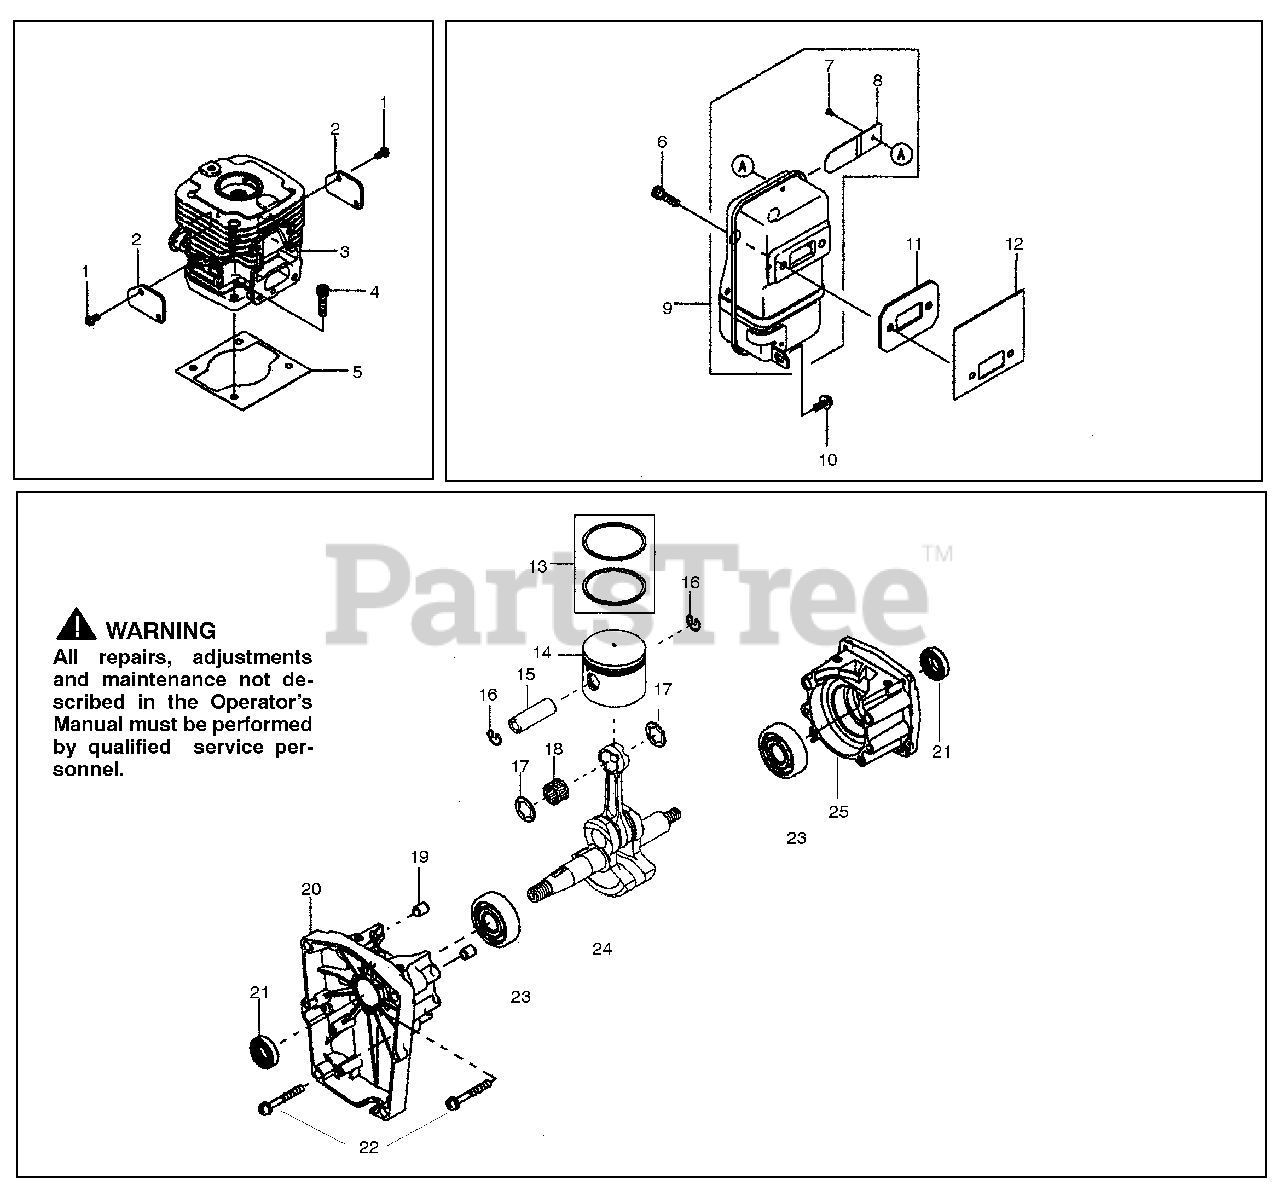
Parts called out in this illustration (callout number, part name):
1	Screw
3	Cylinder-Engine
4	Bolt m5x20
5	Gasket-Cylinder
6	Bolt m6x20
8	Spark Arrestor
9	Assy-Muffler
10	Screw m5x14
13	Ring-Piston (Set)
14	Piston-Engine
15	Pin-Piston
16	Ring-Snap
18	Bearing-Small End
20	Crankcase
21	Seal-Oil (15-25-7-F)
22	Screw m5x40
23	Bearing-Ball
24	Assy-Crankshaft
25	Crankcase "A"
